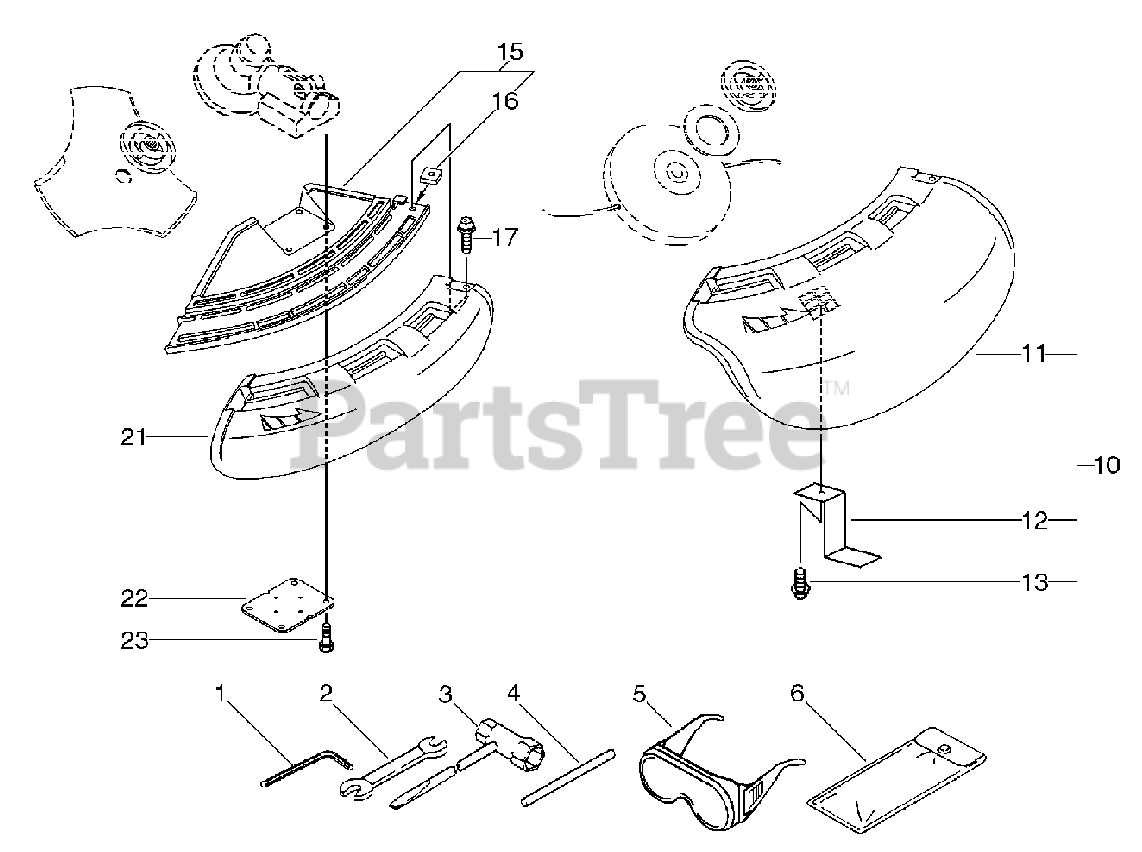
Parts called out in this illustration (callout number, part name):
1	WRENCH, ALLEN 4 MM
2	SPANNER 8×10
3	T-WRENCH 17x-19 L200
4	TOOL, LOCKING 5×120 MM
5	GLASSES, SAFETY
6	BAG, TOOL
10	DEBRIS SHIELD ASSY
11	SHIELD, DEBRIS
12	CUTTER, LINE
13	SCREW, TAPPING 5×12
15	BRACKET ASSY, SHIELD
16	NUT M5
17	SCREW 5×18
21	SHIELD, BLADE
22	PLATE, SHIELD
23	BOLT 5×25
